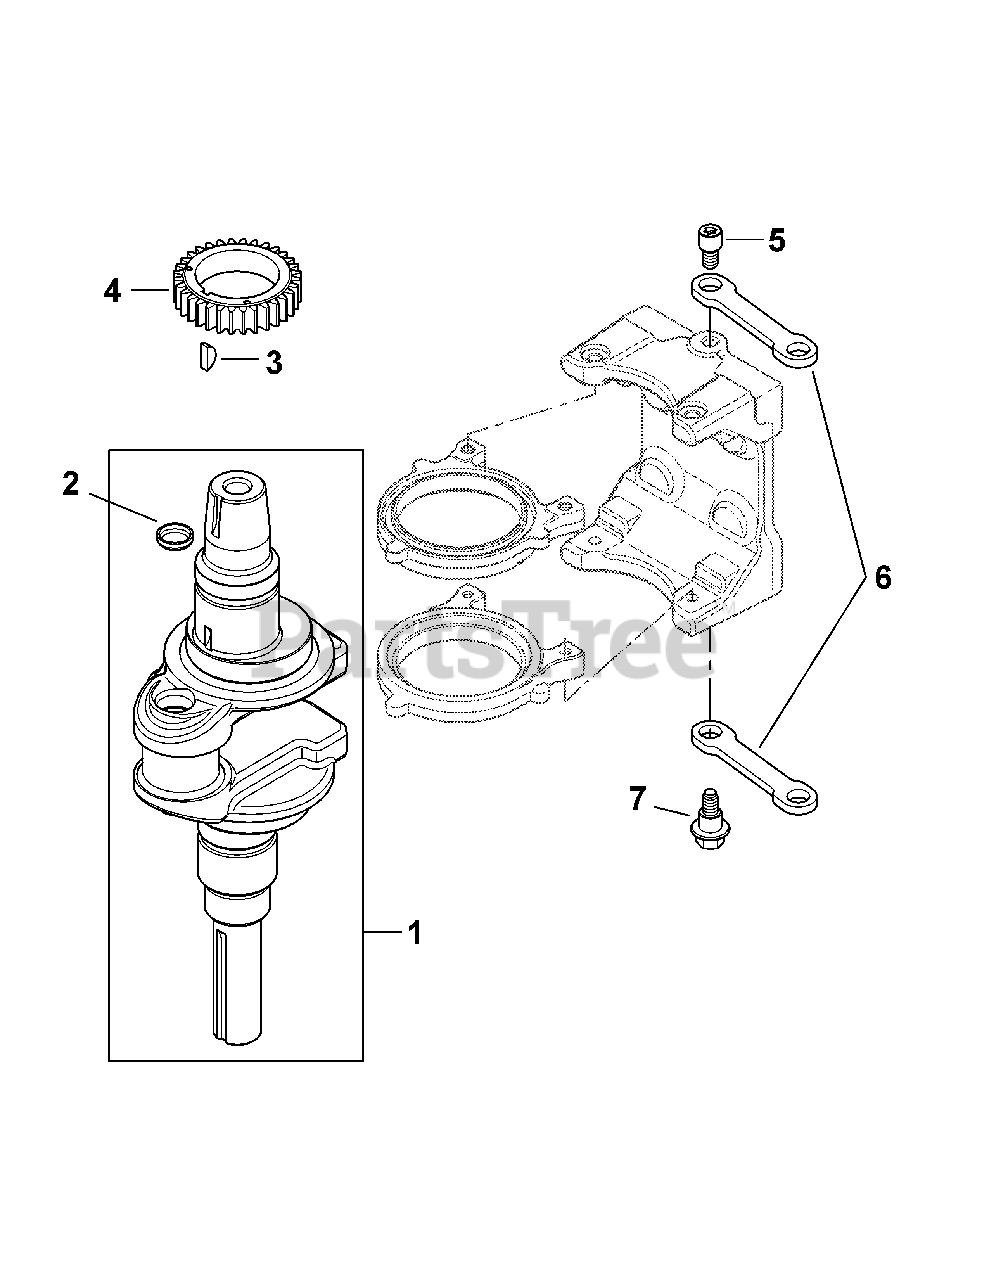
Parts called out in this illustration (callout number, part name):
1	Crankshaft Assembly Kit (Inc. 2)
3	Key, 3/16 X 5/8
4	Crankshaft Gear
5	Link Pivot Screw
6	Balance Weight Linkage
7	Shoulder Screw
